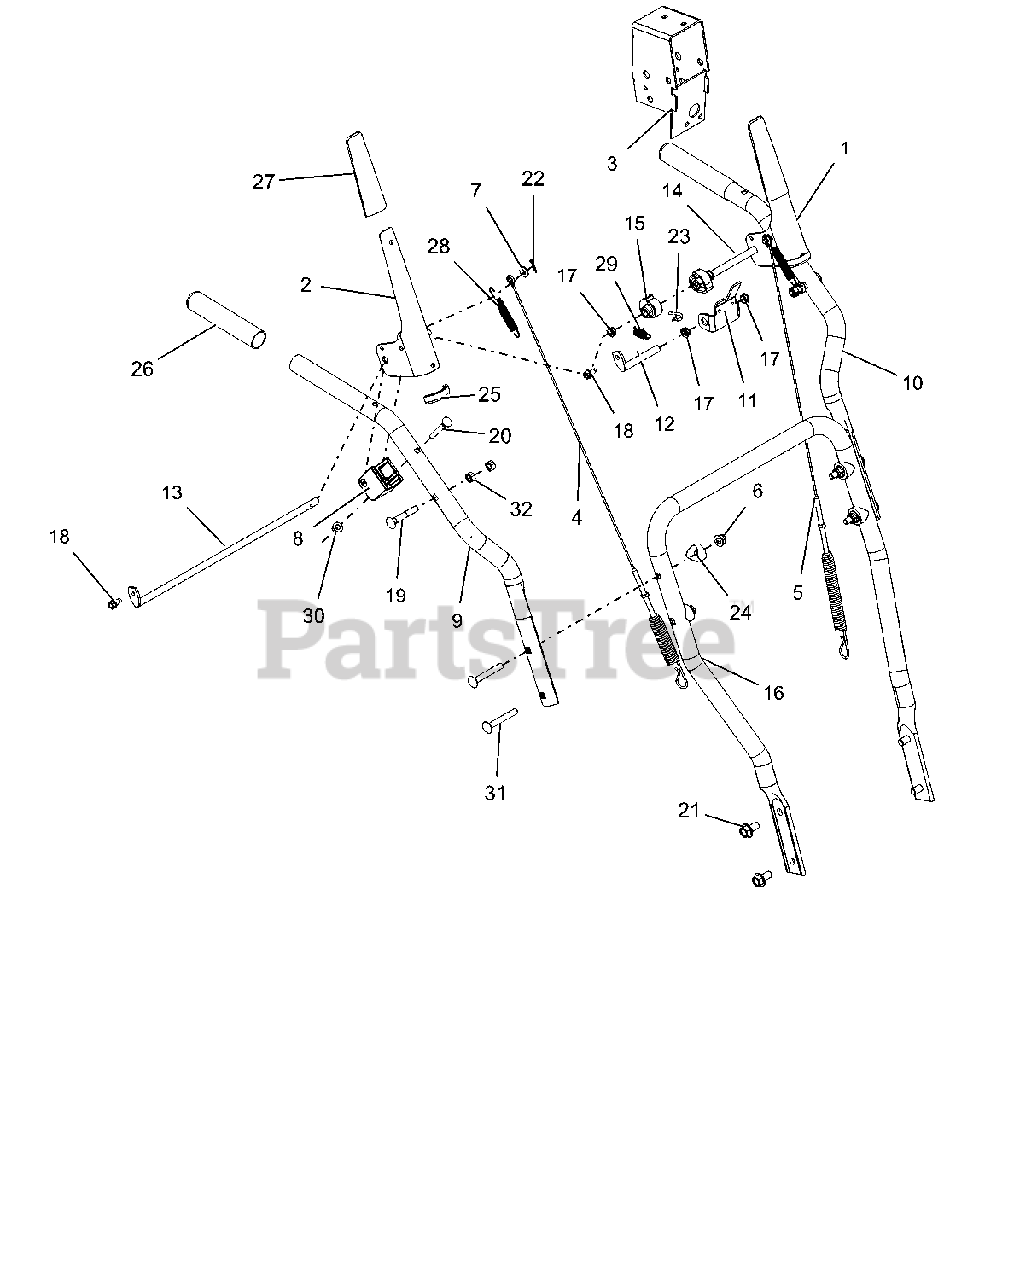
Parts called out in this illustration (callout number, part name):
1	LEVER, CLUTCH-LH
2	LEVER, CLUTCH-RH
3	WELDMENT, BRACKET INTERLOCK
4	CABLE, AUGER (DELUXE & PRO)
5	CABLE, UPPER TRACTION
6	@NUT-LK-NYL-FLG .31-18 YWZC
7	@WSHR-FL-STL.281X.62X.065 YWZC
8	BLOCK, CLUTCH PADDLE
9	HANDLEBAR, UPPER - RH
10	HANDLEBAR, UPPER - LH
11	BRACKET, INTERLOCK ARM
12	ROD, PIVOT - INTERLOCK
13	ROD, PADDLE MOUNT - LONG
14	ROD, PADDLE MOUNT - SHORT
15	CAM, INTERLOCK
16	HANDLEBAR, LOWER - SM DELUXE
17	BUSHING, POLYLINER-.38 SNAPIN
18	SCR-TAP .25-20X.50 HWH TR YWZ
19	BLT-RDHDXLSQNK .31-18X2.0 G5YZ
20	BLT-RDHDXLSQNK .25-20X2.0 G5YZ
21	BLT-SERHFWH .38-16X.75 YWZC
22	PIN-HAIR INT .06X.18X.77
23	PIN, SPRING CLIP
24	SPACER, HANDLEBAR
25	EDGING, CLUTCH PADDLE - 2.00"
26	GRIP,HANDLE-GRAY
27	SLEEVE, CLUTCH PADDLE-GRAY
28	SPRING, EXTENSION
29	SPRING-EXT .047X.438X1.45
30	@NUT-LK-TOP-FLG .25-20 YWZC
31	@BLT-RDHDSQNK .31-18X2.25 G5YZ
32	@NUT-LK-CTR .31-18 YWZC
